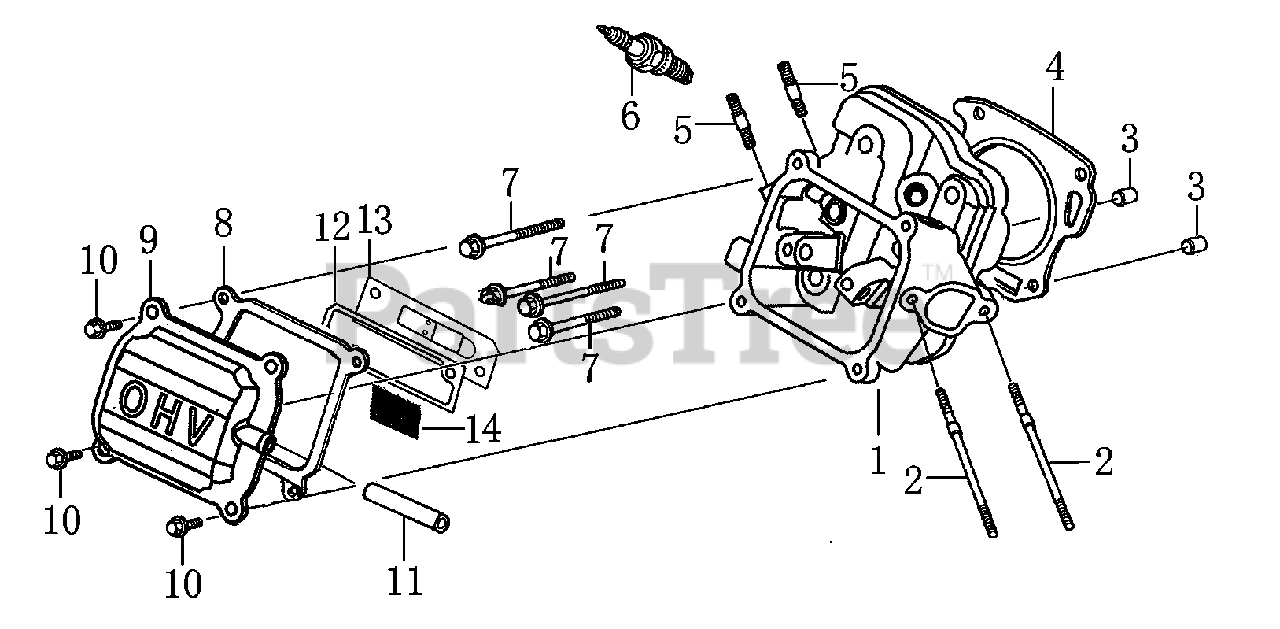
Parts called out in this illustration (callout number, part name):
1	HEAD, CYLINDER
2	BOLT, STUD , IN.
3	PIN, DOWEL
4	GASKET, CYLINDER HEAD
5	BOLT, STUD, EX.
6	PLUG, SPARK
7	BOLT, HEAD, FLANGED
8	GASKET, VALVE COVER
9	COVER, VALVE
10	BOLT, FLANGE
11	TUBE,BREATHER
12	GASKET BREATHER CHAMBER
13	CAP, BREATHER CHAMBER
14	OIL STRAINER
